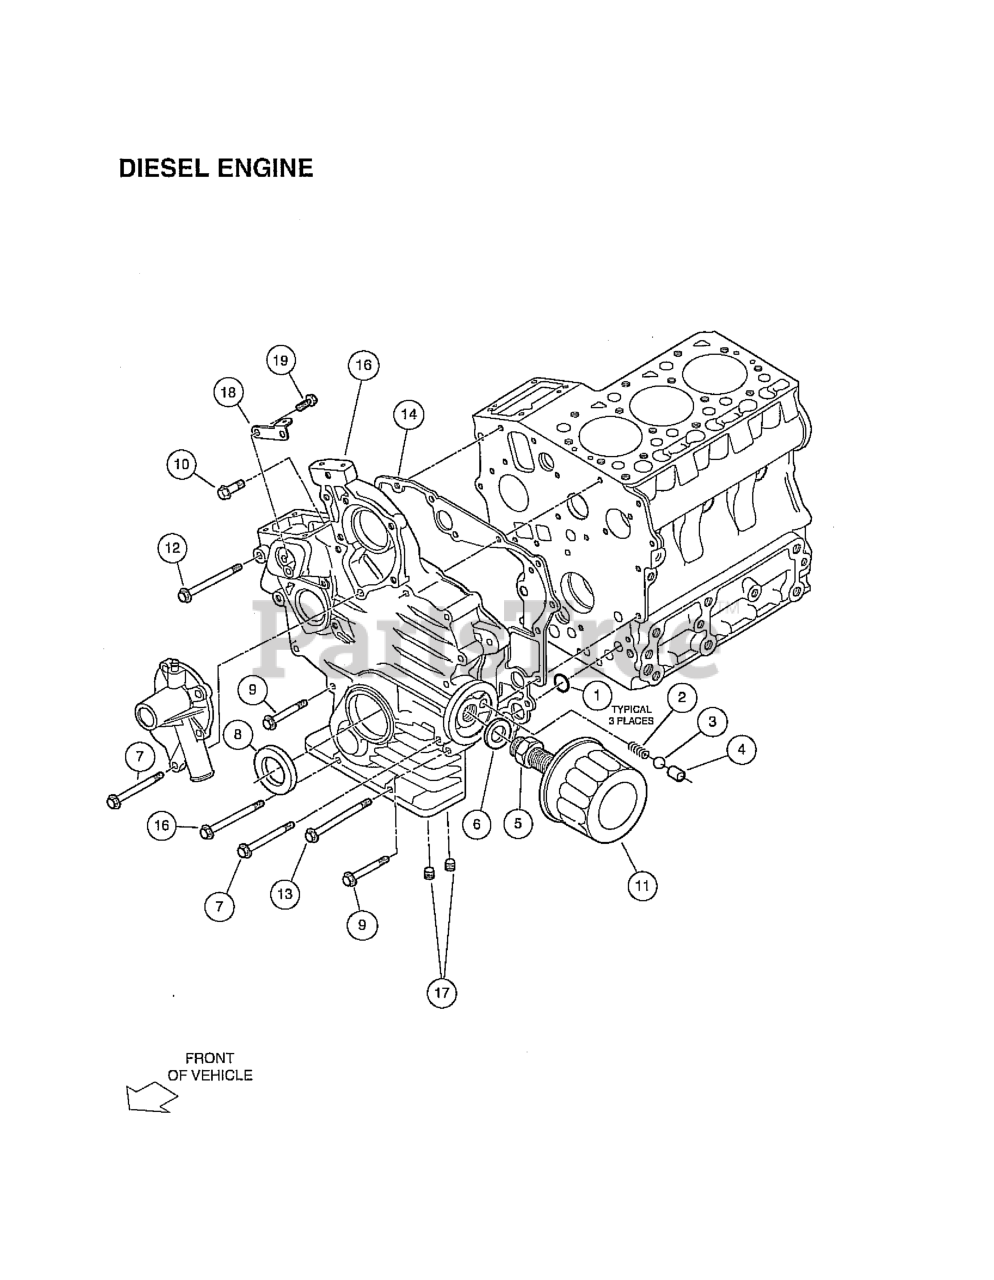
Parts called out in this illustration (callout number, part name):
1	O-RING, 18 X 13
2	SPRING, VALVE
3	BALL, VALVE
4	SEAT, VALVE
5	JOINT, PIPE
6	WASHER, PLAIN, SPECIAL
7	BOLT, M6 X 1 X 60
9	BOLT, D722, FRONT CASE
10	BOLT, D722 INTAKE MANFLD LOWER
11	FILTER, ENGINE OIL,D722
12	BOLT, GEARCASE, TOP
13	BOLT, GEARCASE, LOWER
14	GASKET, GEARCASE, D722
15	CASE-GEAR-COMP
16	PLUG, 1/4" NPT
18	STAY-SPRING-START
